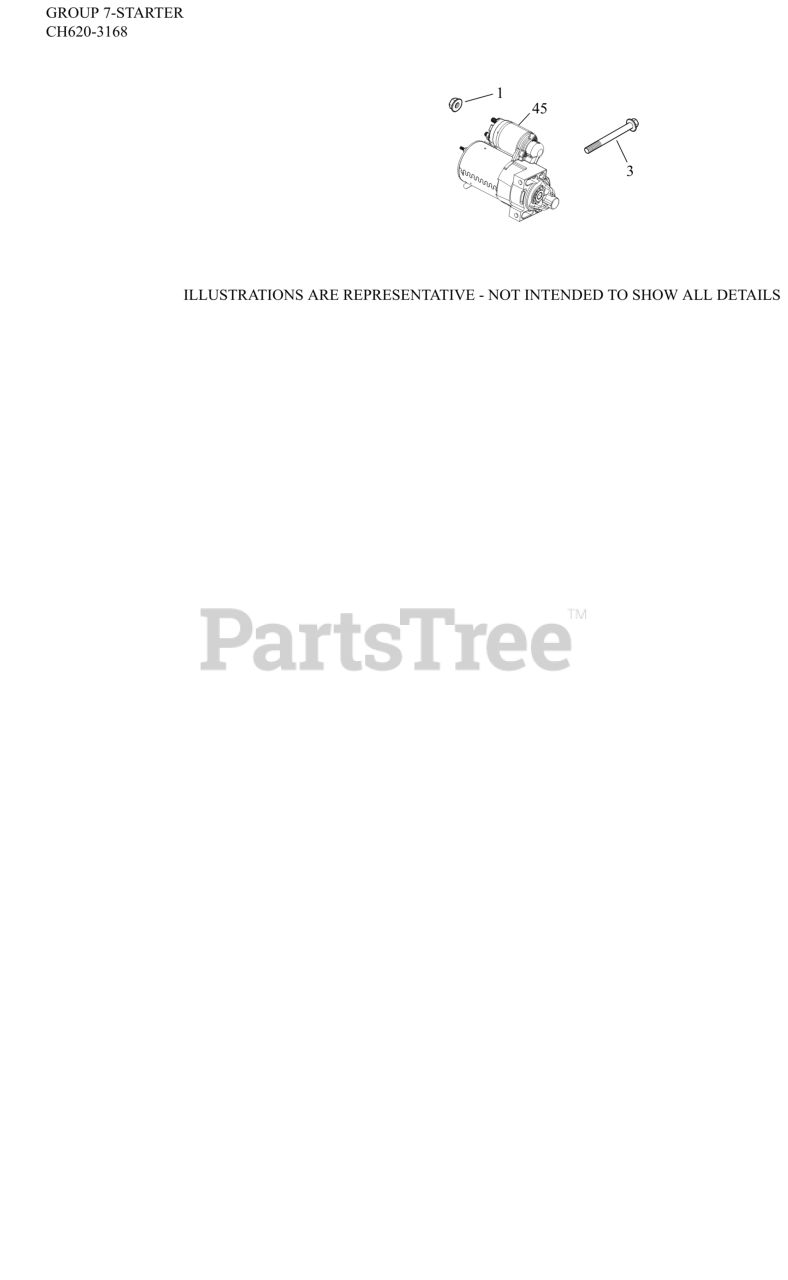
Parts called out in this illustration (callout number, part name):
1	NUT, FLG M8X1.25
3	SCREW, FLG M8X1.25X80
45	STARTER, SOLENOID SHIFT
